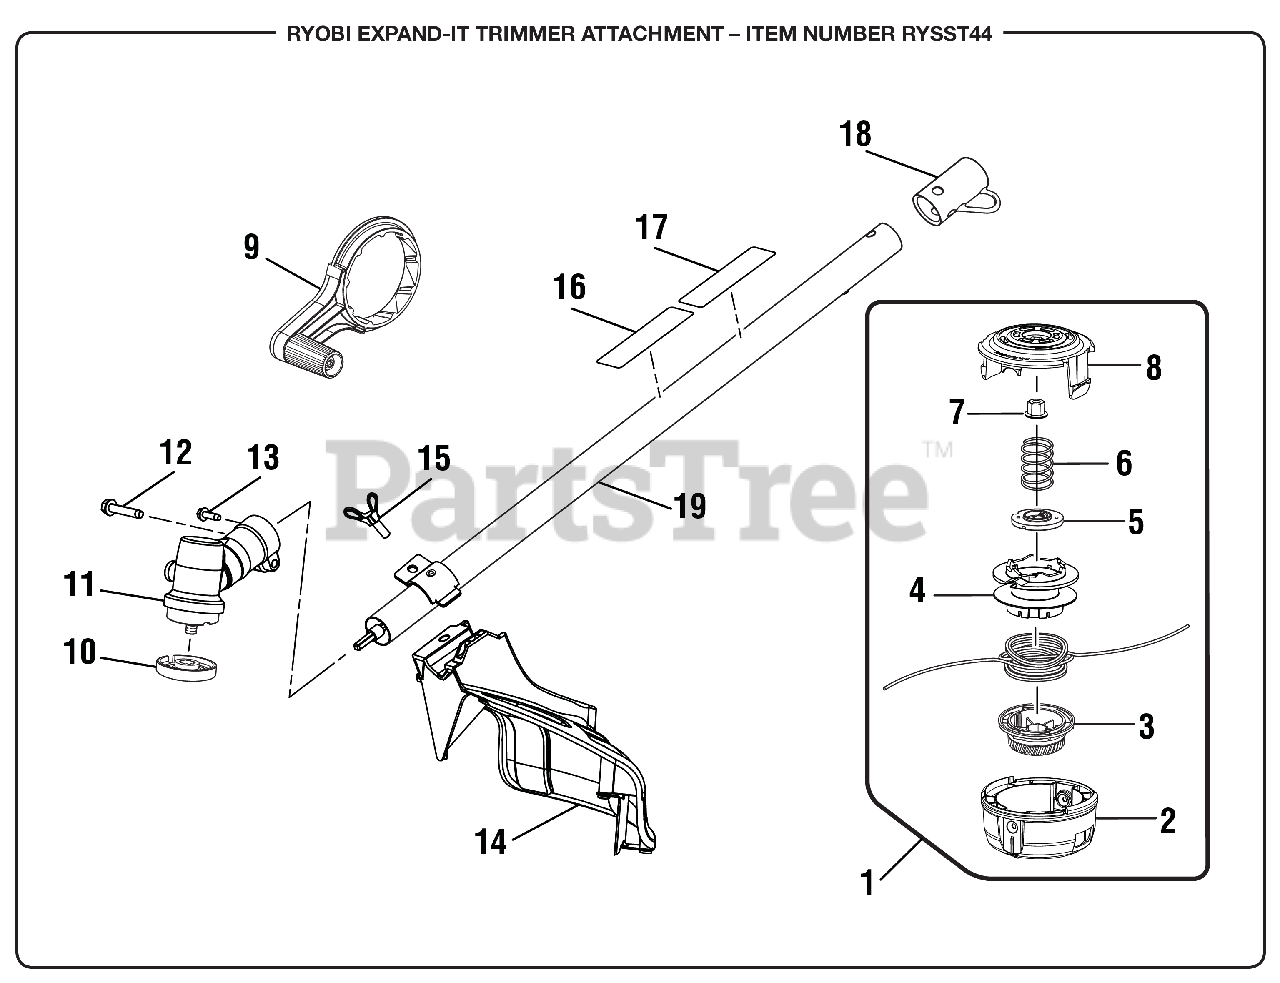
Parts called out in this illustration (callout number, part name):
1	ARBORLESS, RYOBI SS ATTACHMENT
2	Lower Housing
3	Bump Knob (Green)
4	Spool Assembly
5	String Guide
6	Compression Spring
7	Hex Nut (M8, Left Hand Threads)
8	Upper Housing
9	Crank Handle Assembly
10	FLANGED WASHER
11	Gear Case Assembly
12	Screw (1/4-20 x 1-1/4 in., Hex Washer Hd. S.T.)
13	Screw w/Washer (10-24 x 5/8 in., Hex Hd. T.F.)
14	Grass Deflector Assembly (Inc. Key No. 16)
15	Screw (#1/4-20 x 1-1/4 in. Hex Washer Hd.)
16	Ryobi EXPAND-IT Label
17	Warning Icon Label
18	Storage Hanger Cap
19	Straight Shaft Assembly
